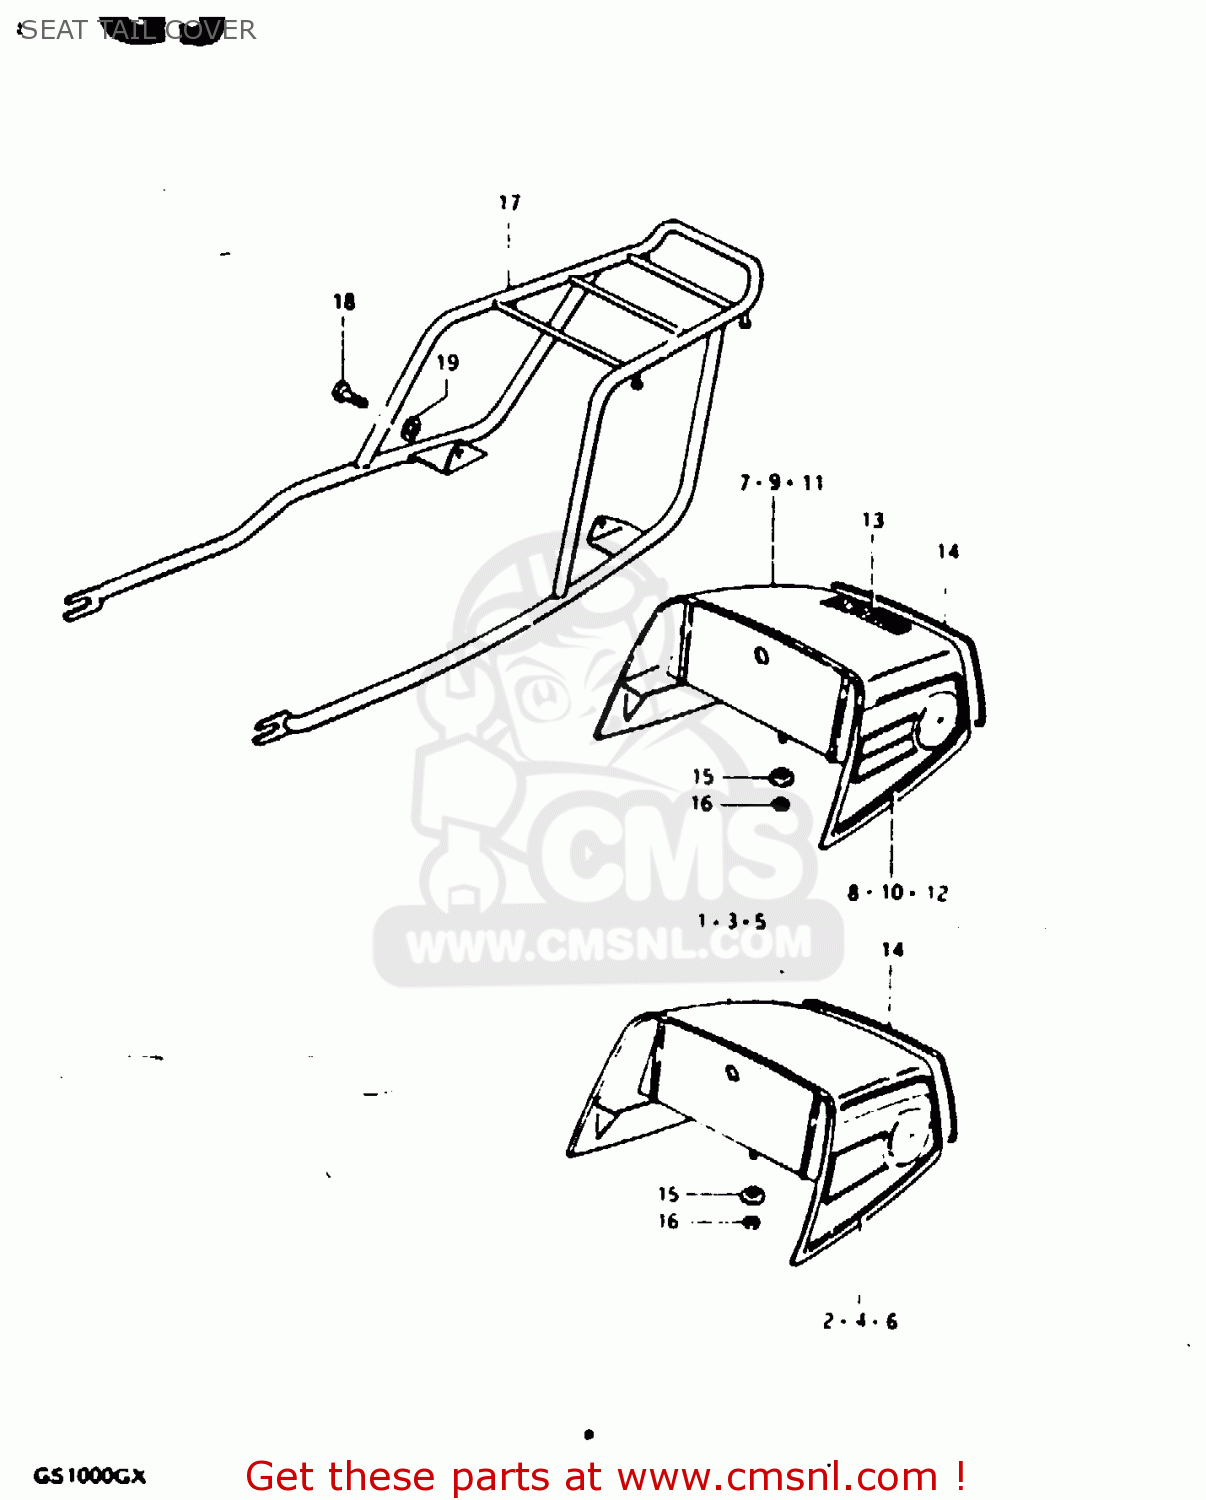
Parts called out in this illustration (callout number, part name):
1	TAIL COVER SET, SEAT
2	TAPE SET
3	TAIL COVER SET, SEAT
4	TAPE SET
5	TAIL COVER SET, SEAT
6	TAPE SET
7	TAIL COVER SET, SEAT
8	TAPE SET
9	TAIL COVER SET, SEAT
10	TAPE SET
11	TAIL COVER SET, SEAT
12	TAPE SET
13	EMBLEM (GOLD/BLACK)
14	MOLDING,SEAT TAIL COVER
15	WASHER
16	NUT 6MM
17	CARRIER
18	BOLT
19	WASHER
